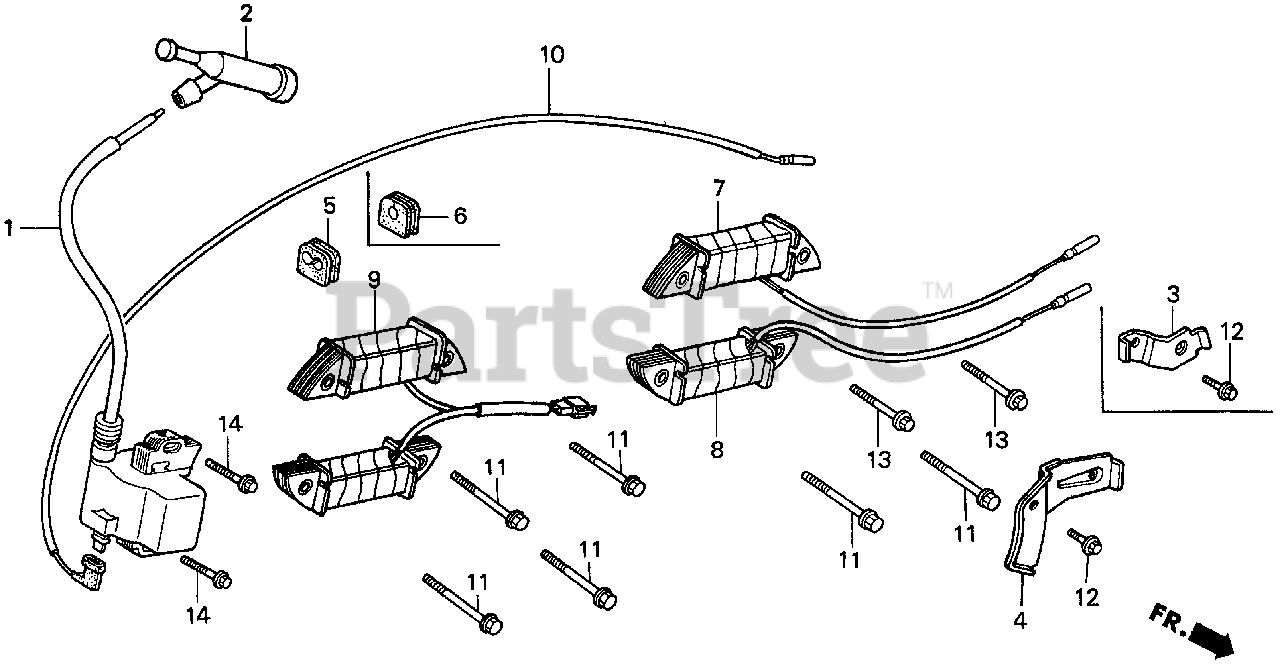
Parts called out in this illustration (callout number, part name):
1	COIL ASSY., IGNITION
2	CAP ASSY., NOISE SUPPRESSOR
5	GROMMET, WIRE
10	WIRE, STOP SWITCH (430MM)
14	BOLT, FLANGE (6X28)
